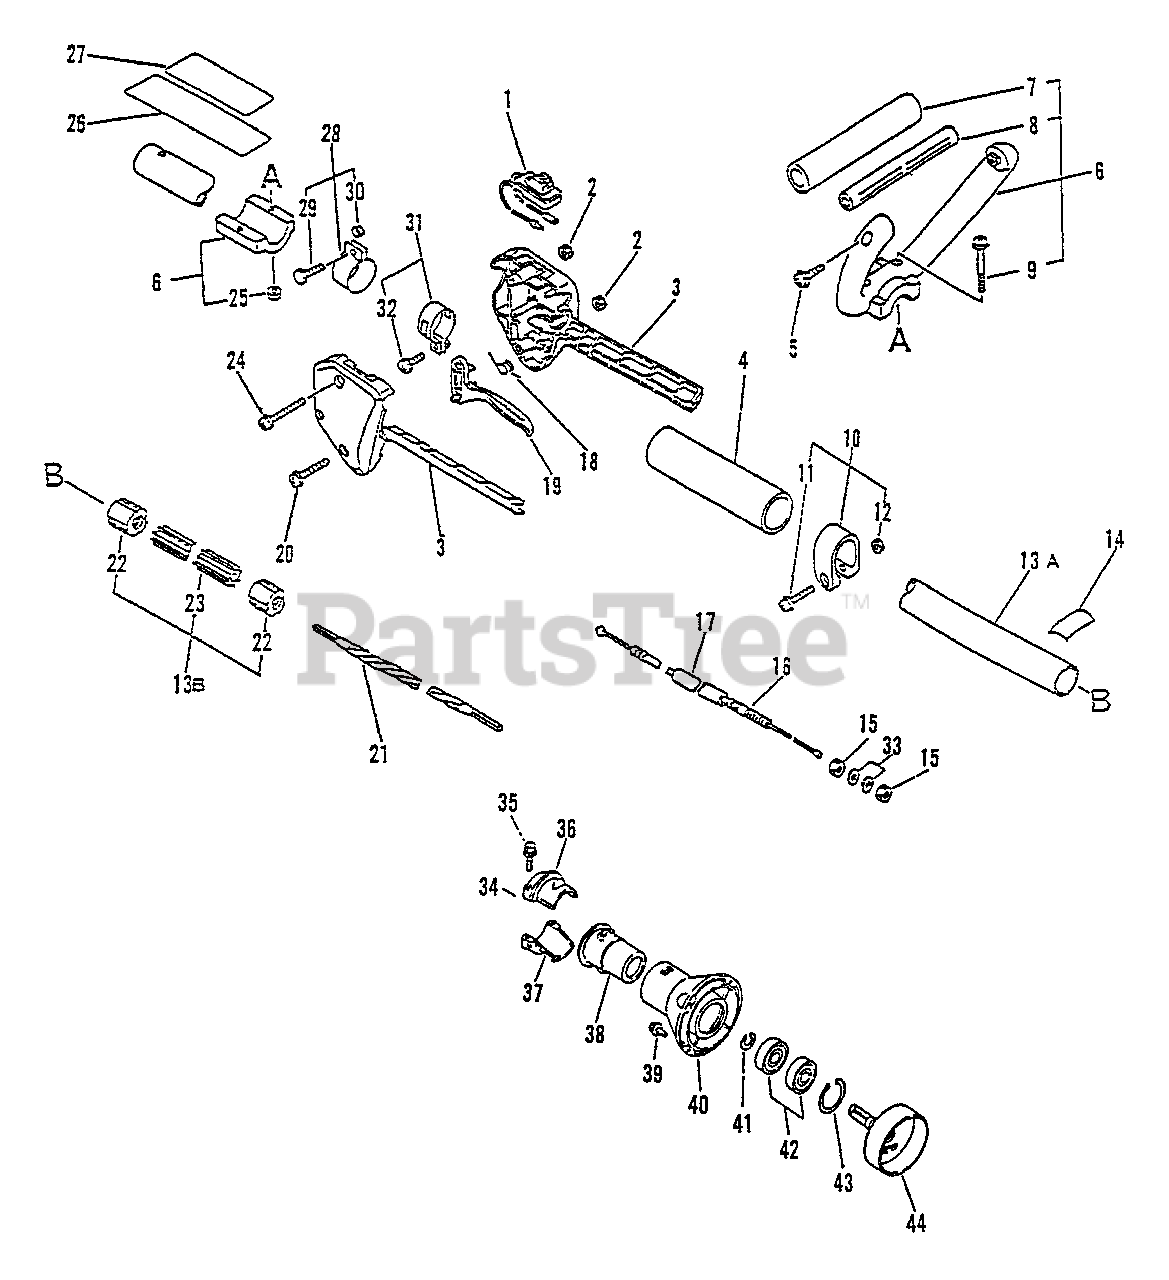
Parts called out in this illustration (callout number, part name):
1	SWITCH, ON-OFF
2	NUT M5
3	HANDLE KIT, CONTROL
4	GRIP, HANDLE
5	SCREW 5×30
6	LOOP HANDLE ASSY
7	GRIP, HANDLE
9	SCREW 6×25
10	CLAMP KIT
11	SCREW 5×30
12	NUT M5
13	MAIN PIPE ASSY 25×1500
13A	MAIN PIPE ASSY 25×1500
13B	MAIN PIPE ASSY 25×1500
14	LABEL - ALIGNMENT
16	CABLE, THROTTLE
17	TUBE - VINYL
18	SPRING, TORSION
19	TRIGGER, THROTTLE
20	SCREW 5×25
21	DRIVESHAFT - FLEXIBLE L= 1522
23	LINER, FLEXIBLE 21.6×1420
24	SCREW 5×35
25	NUT, HEX M6
27	LABEL - CAUTION
28	HOOK
29	BOLT 5×18
30	SPACER, GUARD
31	CLAMP KIT
32	SCREW 5×14
33	WASHER 6.5×11.5×0.8
34	HOLDER KIT
35	BOLT - 5×25
36	HOLDER, MAIN PIPE - UPPER
39	SCREW 5×16
40	CASE, CLUTCH - GRAY
41	RING, RETAINING - 12
42	BEARING, BALL 6001
43	RING, SNAP 28
44	DRUM, CLUTCH
